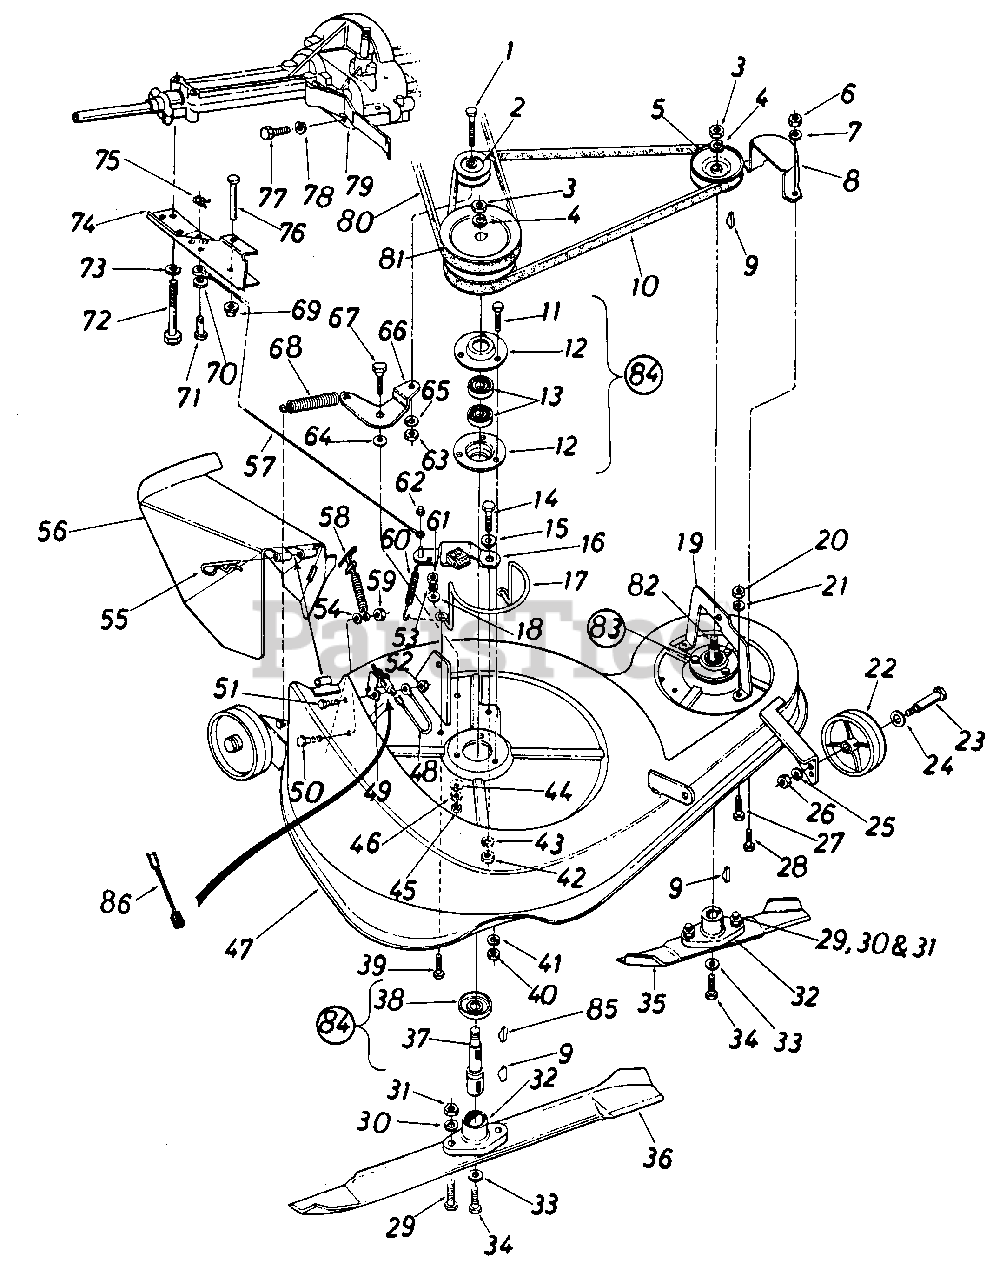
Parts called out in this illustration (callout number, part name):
1	SCREW-HEX 3/8-24 X 1.50 GR.5
2	PULLEY-V-BELT IDLER
3	NUT-HEX JAM 5/8-18
4	WASHER-BELL
6	NUT-HEX 1/4-20
7	LOCK WASHER 1/4 DIA
8	COVER-BELT GUARD
9	KEY-HI-PRO #6-5/32 X 5/8 DIA
10	BELT-V 1/2 X 53
11	SCREW-HEX 5/16-18 X .75
12	HOUSING-BRG
13	BEARING-BALL
14	SCREW-HEX 5/16-18 X 1.00
15	SPACER-SHLD
16	BRACKET ASSY
17	GUARD-BELT
18	WASHER-FL-.344 ID X .88 OD X .063
19	BRACKET-DECK
20	NUT-HEX 5/16-18
21	WASHER-LOCK-5/16
22	WHEEL-PLAS. 5X1.38
23	SCREW-SHLD
24	WASHER-BELL .400 ID X .88 X .060
25	WASHER-LOCK-3/8
26	NUT-HEX 3/8-16
27	SCREW-HEX 5/16-18 X .75
28	SCREW-HEX 1/4-20 C .62
29	SCREW-HEX SPECIAL 5/16-24X1.0
30	WASHER-LOCK-5/16
31	NUT-5/16-24
32	ADAPTER-BLADE
33	WASHER-HDL 3/8
34	SCREW-HEX 3/8-24 X 1.50 GR.5
35	BLADE-13IN
36	BLADE-24IN
37	SPINDLE-BLADE
38	SHIELD-BRG
39	SCREW-HEX 5/16-18 X .75
40	NUT-HEX 5/16-18
41	WASHER-LOCK-5/16
42	NUT-HEX 5/16-18
43	WASHER-LOCK-5/16
44	NUT-HEX 5/16-18
45	NUT-HEX 5/16-18
46	WASHER-LOCK-5/16
47	DECK ASSEMBLY-36 IN
48	WIRE-REV LOCKOUT
50	SCREW-TRUSS MACH 1/4-20 X .50
51	SCREW-HEX 1/4-20 C .62
52	NUT-HEX 1/4-20
53	WASHER-LOCK-5/16
54	WASHER-FL-.281 ID X .50 OD X .063
55	PIN-COTTER
56	DEFLECTOR-CHUTE
57	CABLE ASSY-BRAKE
58	LOCK ASSY-HOOD
59	NUT-HEX 1/4-20
60	SPRING-EXTENSION
61	NUT-HEX 5/16-18
63	NUT-HEX 3/8-16
64	WASHER-FL-.344 ID X .88 OD X .063
65	WASHER-LOCK-3/8
66	BRACKET ASSY-IDLER
67	SCREW-SHLD
68	SPRING-EXTENSION
70	WASHER-FL-.281 ID X .50 OD X .063
71	PIN-CLEVIS-1/4X1/2
72	SCREW-HEX 5/16-18 X 2.75
73	WASHER-LOCK-5/16
74	GUARD-BELT-LOWER
75	PIN-INTERN COT-5/16 DIA
77	SCREW-HEX 1/4-20 C .62
78	LOCK WASHER 1/4 DIA
79	GUARD-BELT
80	BELT-V 1/2 X 50
82	SPINDLE-BLADE
83	SPINDLE
84	SPINDLE ASSY-BLADE
85	KEY-3/16 X 5/8
